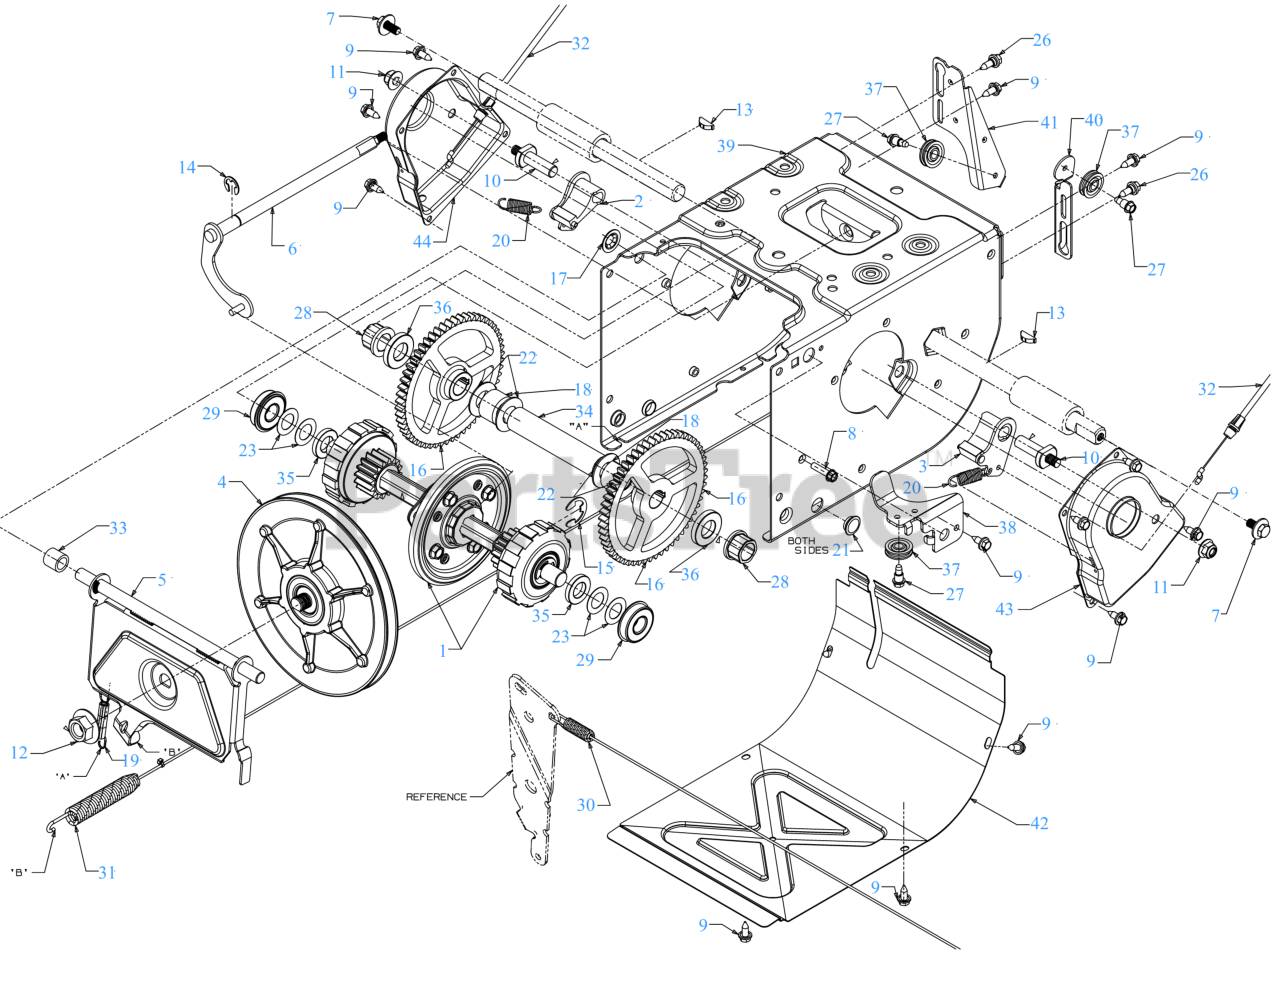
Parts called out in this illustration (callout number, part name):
1	PLANETARY FRICTION WHEEL HEX SHAFT
1	CARRIER ASSEMBLY
1	FRICTION WHEEL ASSEMBLY
2	DOGG ASSEMBLY (RH)
3	DOGG ASSEMBLY (LH)
4	FRICTION WHEEL DISC ASSEMBLY
5	FRICTION WHEEL BRACKET (POWDER BLACK)
6	SHIFT ROD ASSEMBLY
7	SCREW 5/16-24 x .750 GR5
8	SCREW 1/4-20 x 1.00
9	SCREW 1/4-20X.625
10	ACTUATOR SHAFT
12	FLANGE NUT 5/8-18
13	KEY 3/16 x 3/4
14	E-RING FOR .500 SHAFT
15	RETAINING RING
18	SPACER: .76ID x .75
19	EXTENSION SPRING
20	EXTENSION SPRING
22	FLAT WASHER .760ID X1.49OD x .06
23	FLAT WASHER .67X 1.174X .02
26	SHOULDER SCREW
27	SHOULDER SCREW
28	FLANGE BEARING
29	BALL BEARING W/RET
30	AUGER DRIVE CABLE 47.48"
31	WHEEL DRIVE CABLE 44.955"
32	STEERING CABLE
33	SPACER-.513 ID x .703 OD x .69
34	AXLE SUPPORT TUBE
36	AXLE SPACER
37	CABLE GUIDE ROLLER
38	AUGER CABLE BRACKET (POWDER BLACK)
39	DRIVE FRAME
40	AUGER CABLE GUIDE BRACKET
41	GUIDE BRACKET
